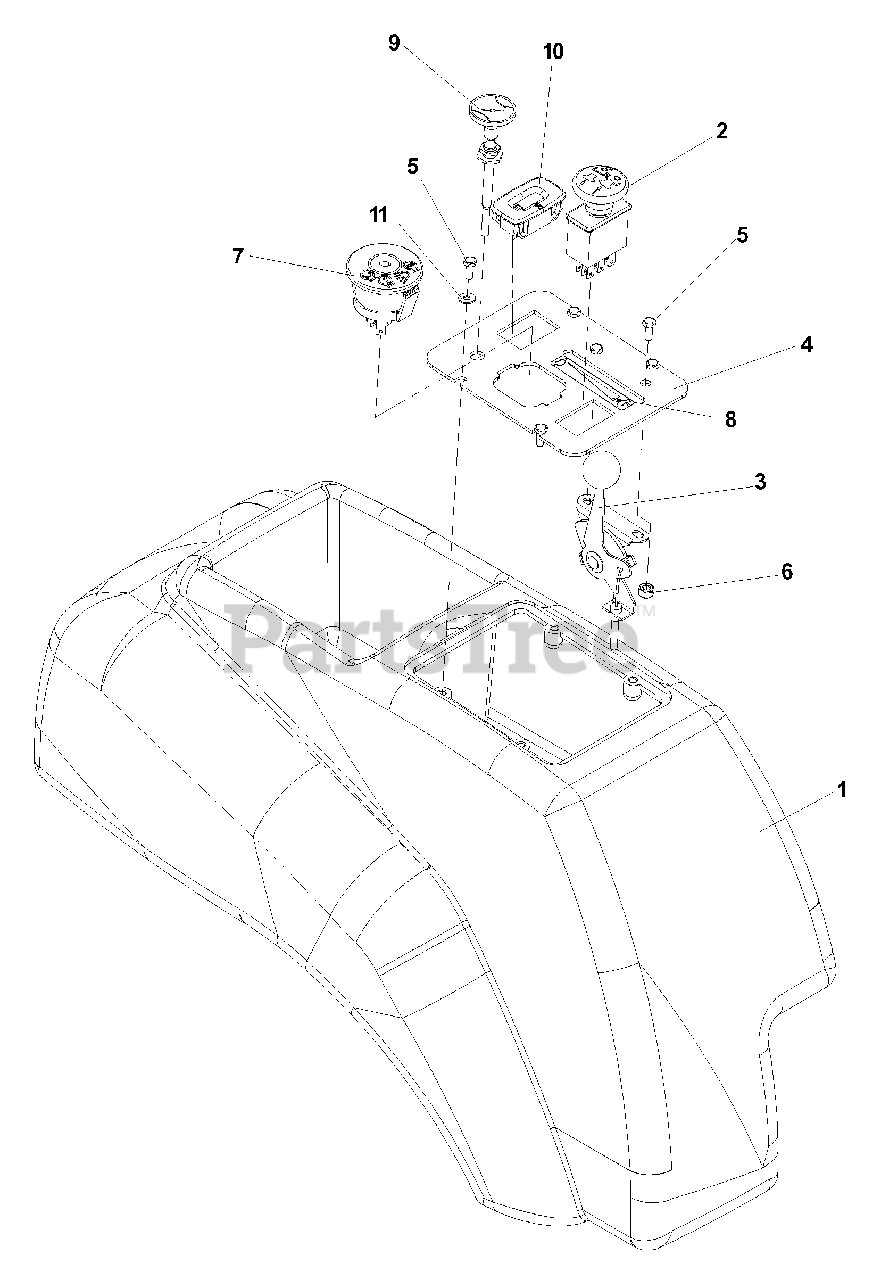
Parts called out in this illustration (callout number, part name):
2	CLUTCH SWITCH
3	THROTTLE CABLE
4	CONSOLE PLATE
5	HCS, #10-24 X 1/2
6	NUT, #10-24, NYLOC
7	IGNITION SWITCH
8	DECAL, THROTTLE
9	CHOKE CONTROL
9	CHOKE CABLE
10	HOUR METER
11	WASHER, #10
